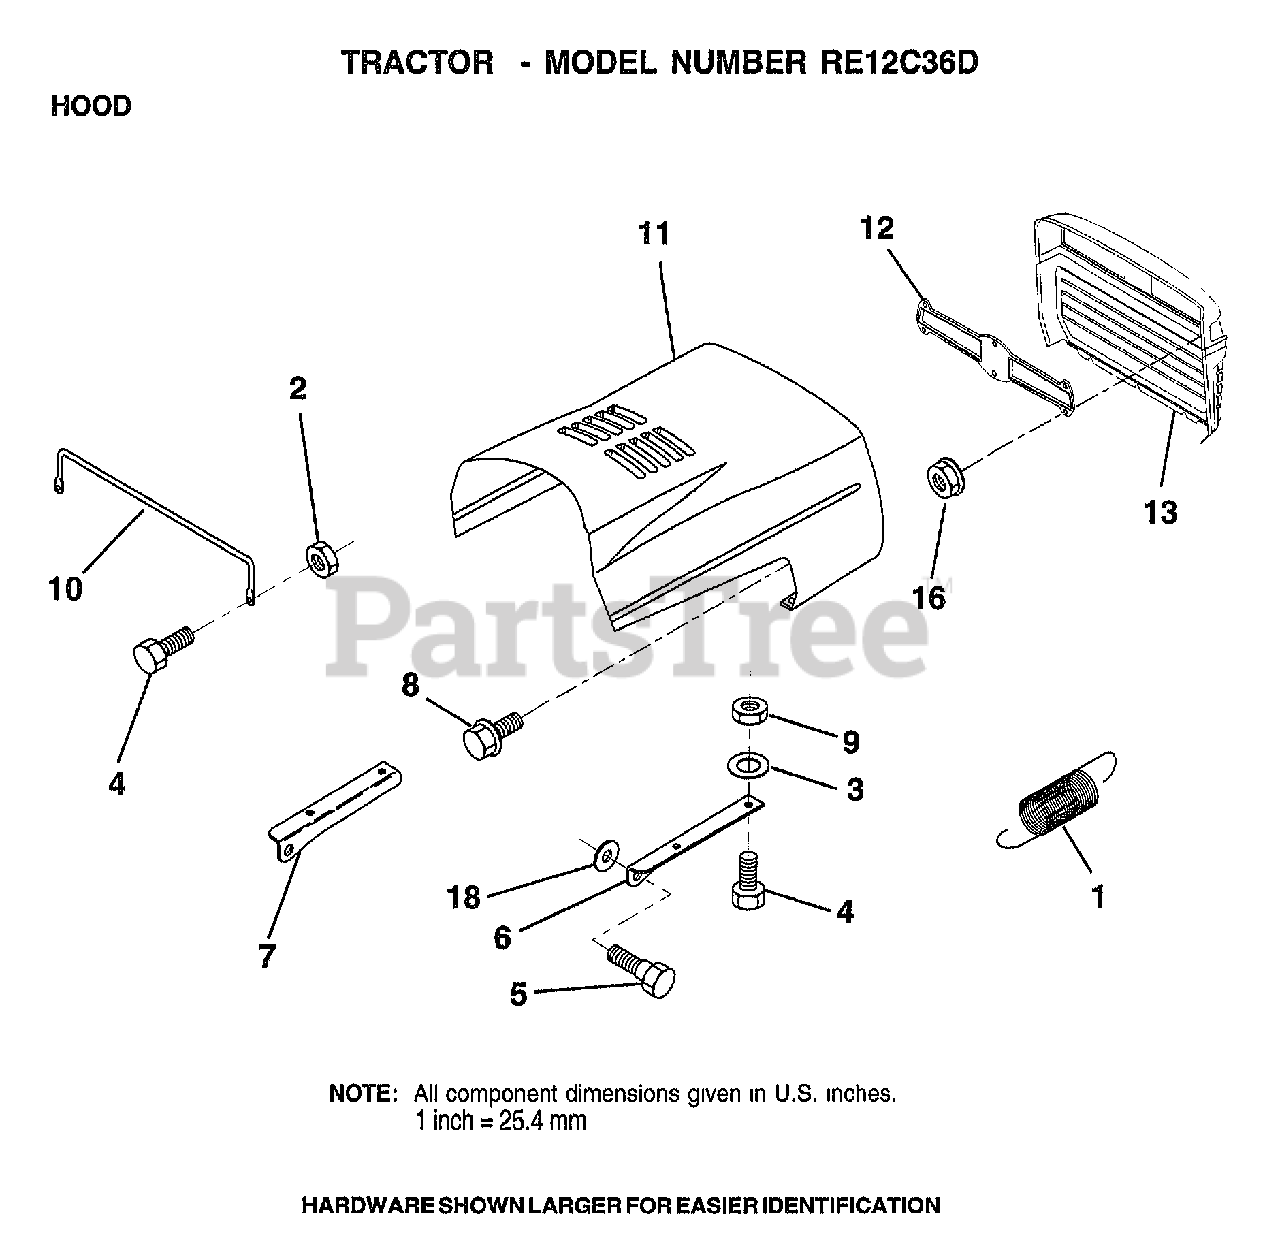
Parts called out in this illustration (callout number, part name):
1	EXT SPRING
2	NUT
3	WASHER
5	BOLT.SHLD.5/16-18
6	BRKT HOOD RH
7	BRKT HOOD LH
8	"SCREW,HWHD.HI-LO#13-16X3/4"
9	NUT
10	"BRACE,HOOD"
11	HOOD
13	GRILL (BLACK)
16	NUT
18	WASHER
